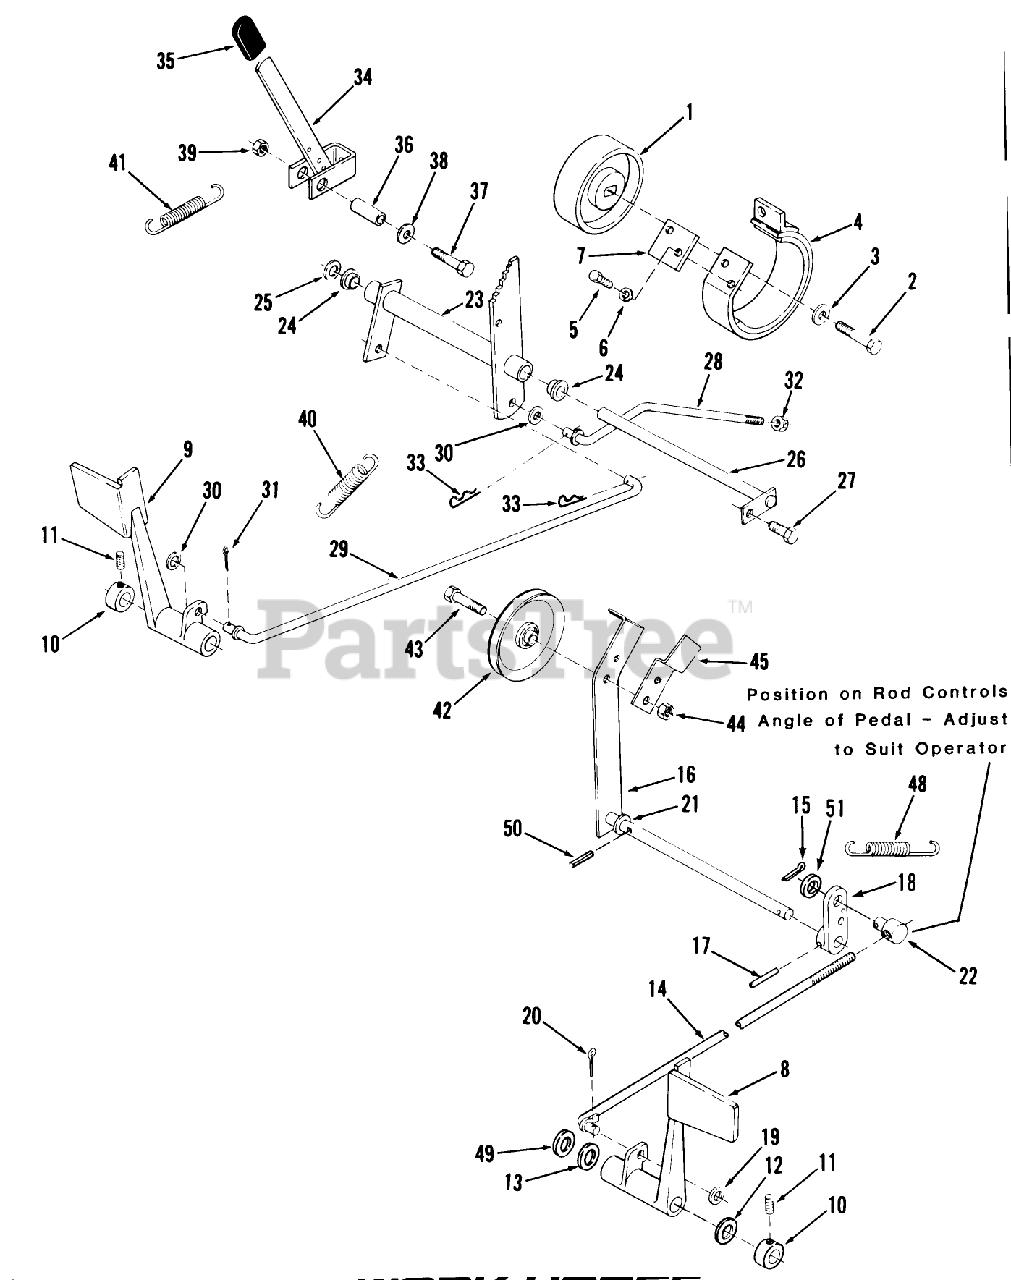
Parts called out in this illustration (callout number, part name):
1	DRUM-BRAKE
2	SCREW-HEX HD CAP
3	WASHER
4	BRAKE BAND ASM
9	PEDAL-BRAKE *R
12	WASHER-BOWED
13	WASHER
14	ROD AND GUIDE ASM
17	PIN-SPIROL
19	WASHER-NYLON
21	SHIM-WASHER
22	TRUNNION
24	BUSHING-FLANGED
26	ROD ASM
27	SCREW
28	ROD-REAR BRAKE
30	WASHER-NYLON
33	Hairpin
35	GRIP
36	SPACER
37	Bolt 3/8-16 x 1 3/4
40	SPRING-BRAKE
41	SPRING-EXTENSION
43	BOLT-SPECIAL HEX
48	SPRING-CLUTCH
50	PIN-SPIROL
